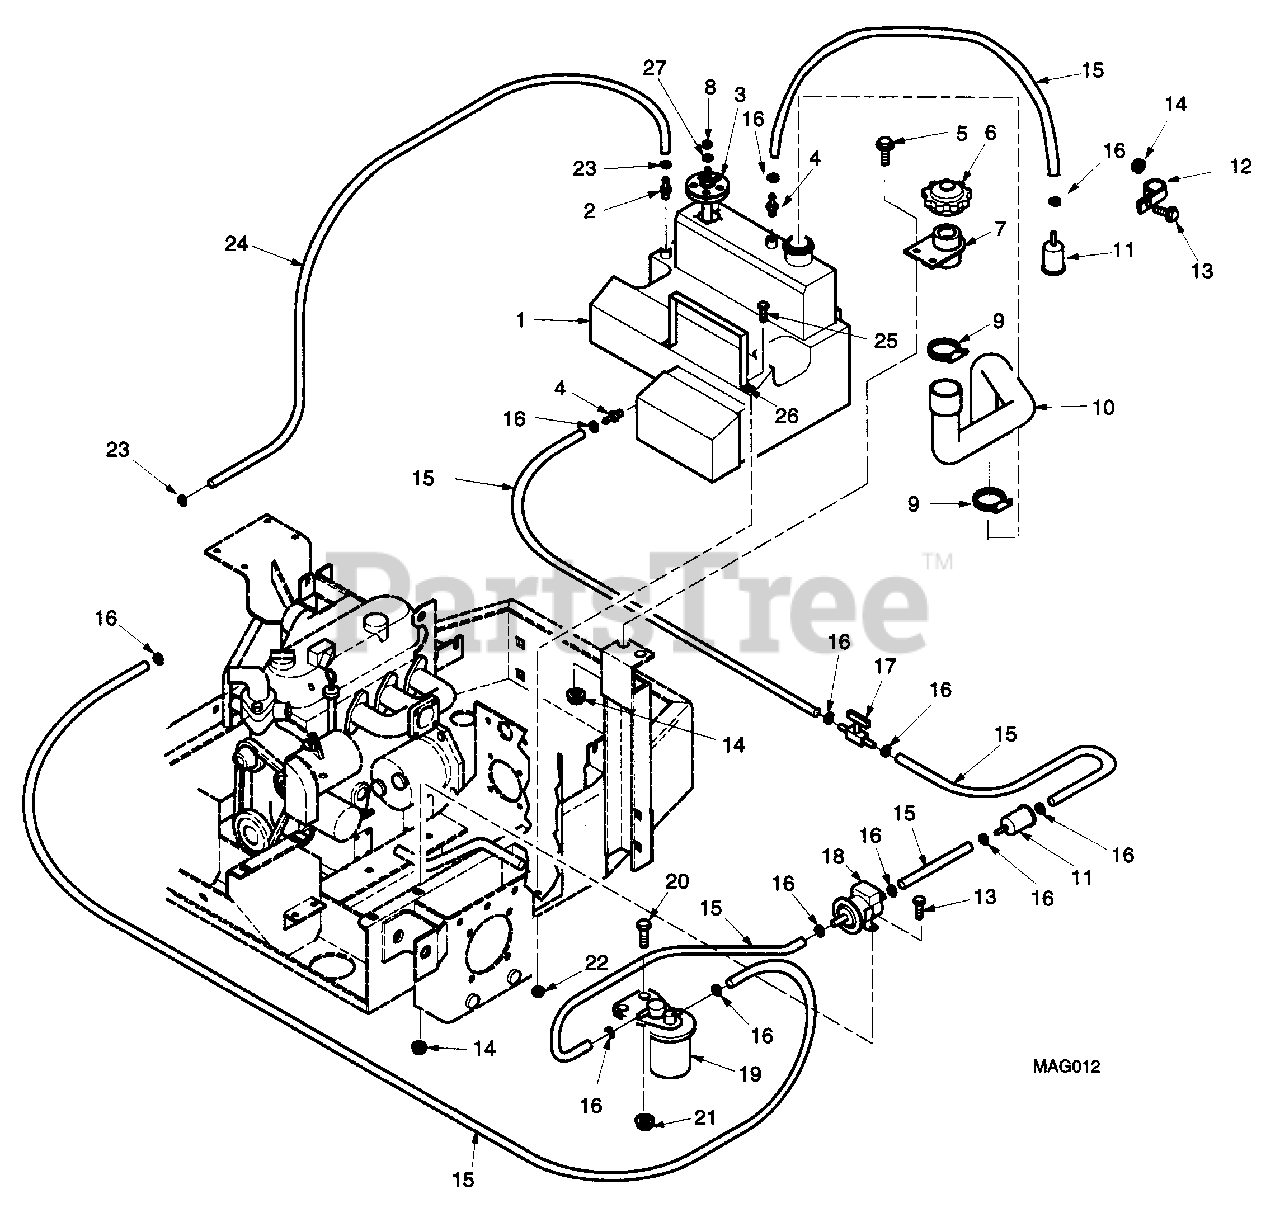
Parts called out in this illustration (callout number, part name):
1	FUEL TANK(INCLUDES 2, 3, 4)
2	FITTING, RETURN LINE
3	SENDER UNIT, FUEL LEVEL(INCL GASKET&SCREWS)
4	FITTING, HOSE
5	SERR. FL. HEX HEAD CAPSCREW, 5/16-18 X 3/4
6	CAP, DIESEL FUEL
7	FILL NECK
8	HEX NUT, #10-32
9	CLAMP, HOSE
10	HOSE, FUEL FILL
11	FUEL PRE-FILTER
12	CLAMP, FUEL FILTER
13	SERR. FL. HEX HEAD CAPSCREW, 1/4-20 X 3/4
14	SERR. FL. HEX NUT, 1/4-20
15	HOSE, FUEL LINE, 5/16
16	CLAMP HOSE
17	VALVE, FUEL SHUTOFF
18	FUEL PUMP, ELECTRIC
19	FUEL FILTER
20	SERR. FL HEX HEAD CAPSCREW 5/16-18 X 1
21	SERR. FL. HEX NUT, 5/16-18
22	HEX LOCKNUT, ELASTIC STOP, 1/4-20
23	FUEL HOSE CLAMP, 3/16
24	HOSE FUEL LINE, 3/16
25	SERR. FL. HEX HEAD CAPSCREW, 1/4-20 X 1-1/2
26	STRAP, FUEL TANK
27	LOCKWASHER, #10
